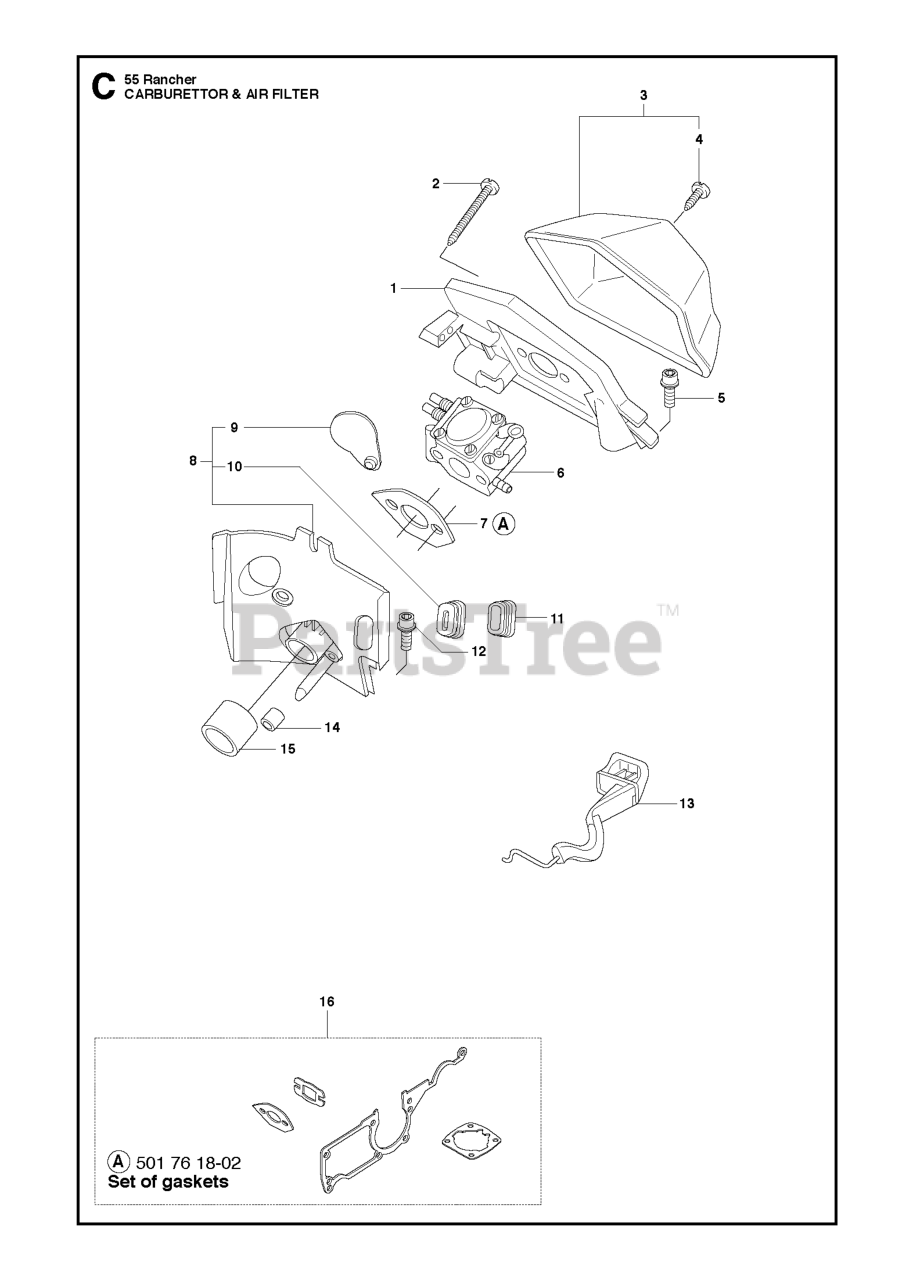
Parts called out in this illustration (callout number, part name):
1	AIR FILTER HOLDER
3	AIR FILTER-NYLON
3	AIR FILTER-FELT
5	SCREW
6	CARBURETOR CIQ-EL7 EPA ZAMA
6	CARBURETOR CIQ-EL6 ZAMA
9	COVER
13	RP CHOKE CONTROL
14	IMPULSE PIPE
15	INDUCTION PIPE
16	GASKET SET
